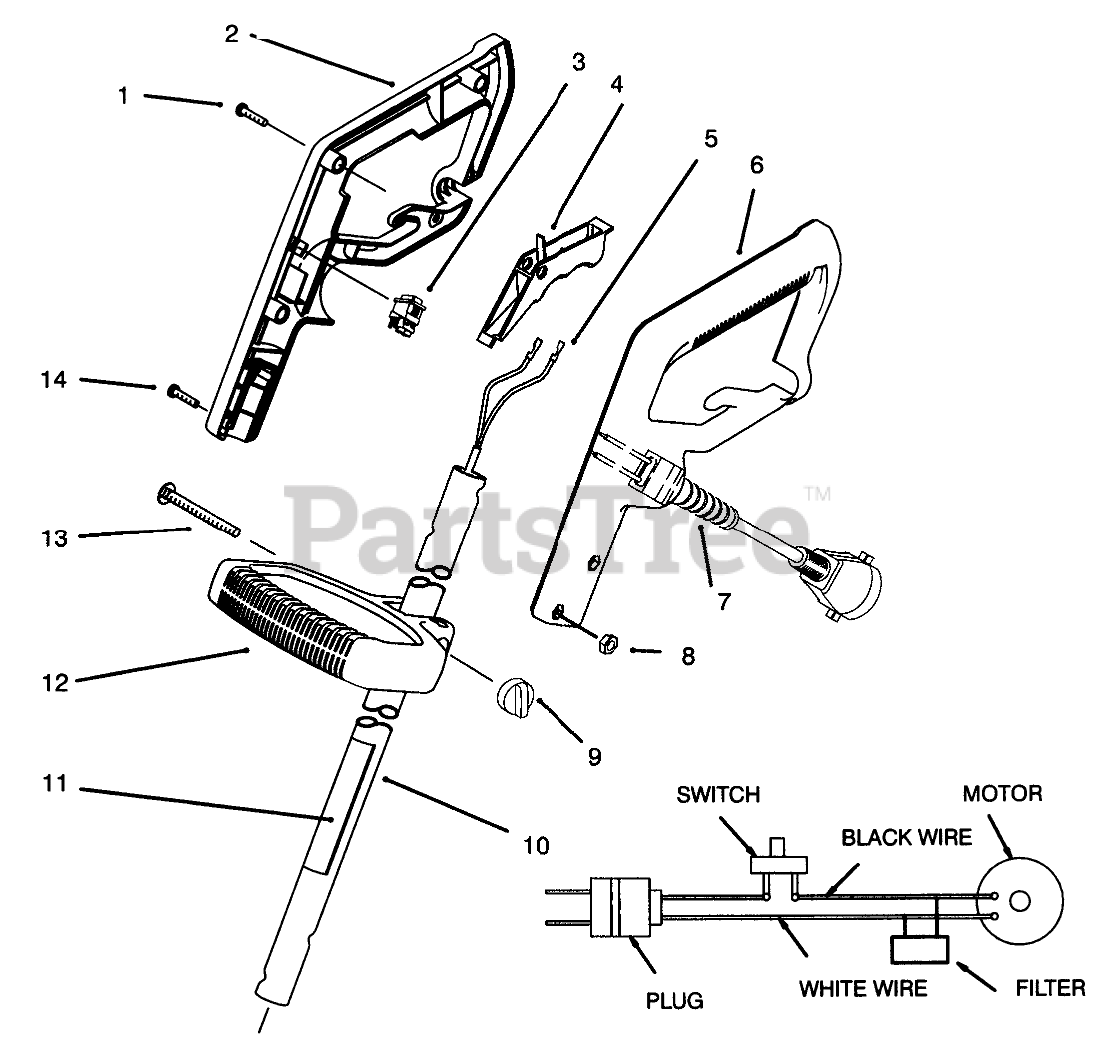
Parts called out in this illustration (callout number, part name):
1	Screw
2	HAND GRIP RH
3	SWITCH - 230V
4	TRIGGER
5	HARNESS - WIRE
6	HAND GRIP LH
7	CORD - POWER
8	NUT-HEX
9	KNOB, VFL/FFL
10	Tube Assembly (Incl. Ref. #11)
11	DECAL - WARNING
12	MID HANDLE
13	SCREW-CARR
14	SCREW-PPH
